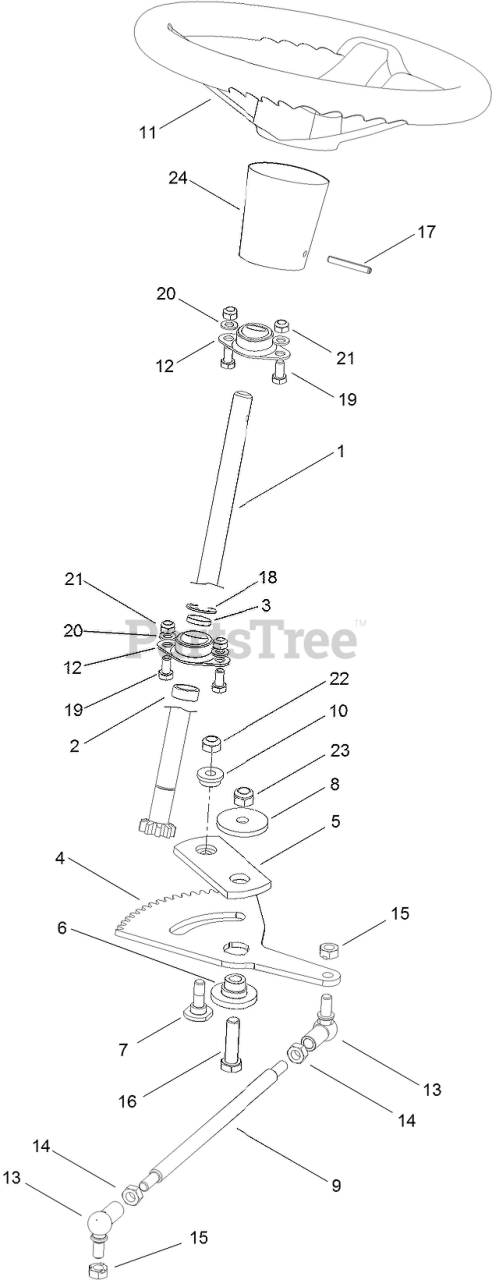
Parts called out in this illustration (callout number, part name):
1	SHAFT-STEERING
2	SPACER-LOWER
3	SPACER-UPPER
4	GEAR-SECTOR
5	Plate-Steering
6	Pivot-Steering
7	Bolt-Shoulder
8	WASHER
9	LINK-DRAG
10	Bushing
11	WHEEL-STEERING
12	BEARING-SPHERICAL
13	JOINT-BALL, ANGLE
14	NUT-HEX
15	NUT-LOCK, NI
16	SCREW-HH
17	PIN-SPIROL
18	CLIP-SPRING
19	SCREW-HH
20	WASHER-PLAIN
21	NUT-LOCK, NI
22	NUT-LOCK
23	NUT-HEX
